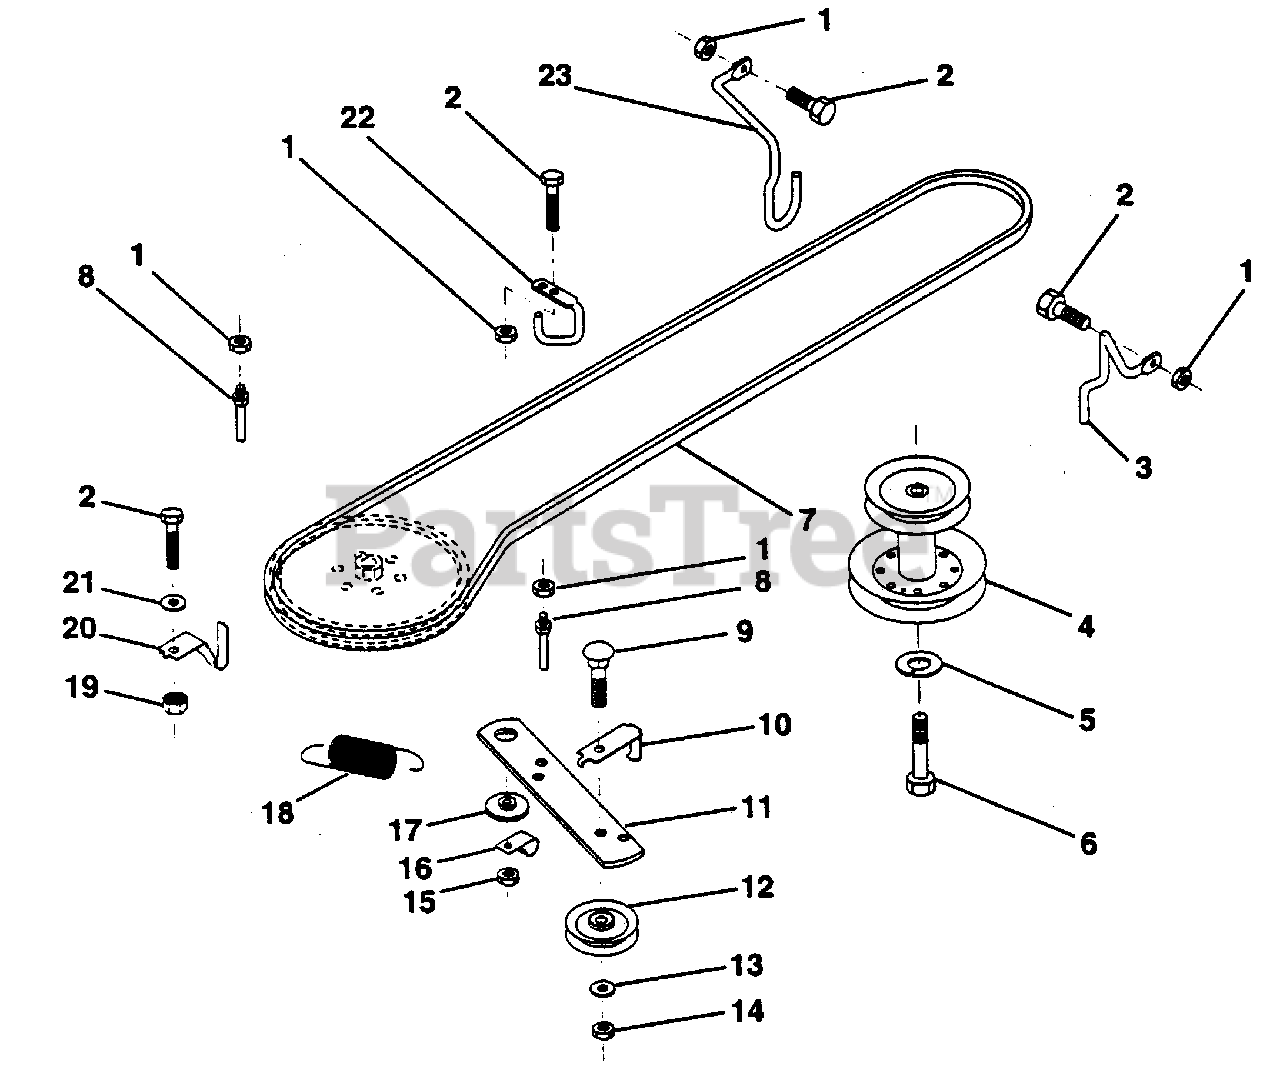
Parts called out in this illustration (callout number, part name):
1	Locknut, Hex w/Ins 5/16-18 (AYP part number)
2	Bolt, Hex Hd 5/16-18 UNC x 3/4 (AYP part number)
3	Keeper, Mower Drive, R. H. (AYP part number)
4	Pulley, Engine (AYP part number)
5	Washer, Lock 7/16 (AYP part number)
6	Bolt Hex 7/16-20 Gr. 5 (AYP part number)
7	Traction, V-Belt Drive (AYP part number)
8	Keeper, T/A Ground Drive Belt (AYP part number)
9	Bolt, Carr. 3/8-16 UNC x 1-1/2 (AYP part number)
10	Keeper, Belt Ground Drive Idler (AYP part number)
11	Arm, Ground Drive Clutch (AYP part number)
12	Idler, Flat (AYP part number)
13	Washer 13/32 x 13/16 x 16 Ga. (AYP part number)
14	Nut, Centerlock 3/8-16 UNC (AYP part number)
15	Nut, Lock Hex w/Wsh 3/8-16 UNC (AYP part number)
16	Clip, Insulated (AYP part number)
17	Spacer, Retainer (AYP part number)
18	Spring Extension (AYP part number)
19	Nut, Keps 5/16-18 UNC (AYP part number)
20	Keeper, T/A Ground Drive Belt (AYP part number)
21	Washer 11/32 x 5/8 x 16 Ga. (AYP part number)
22	Keeper, Frame Ground Drive Belt (AYP part number)
23	Keeper, Mower Drive, L. H. (AYP part number)
